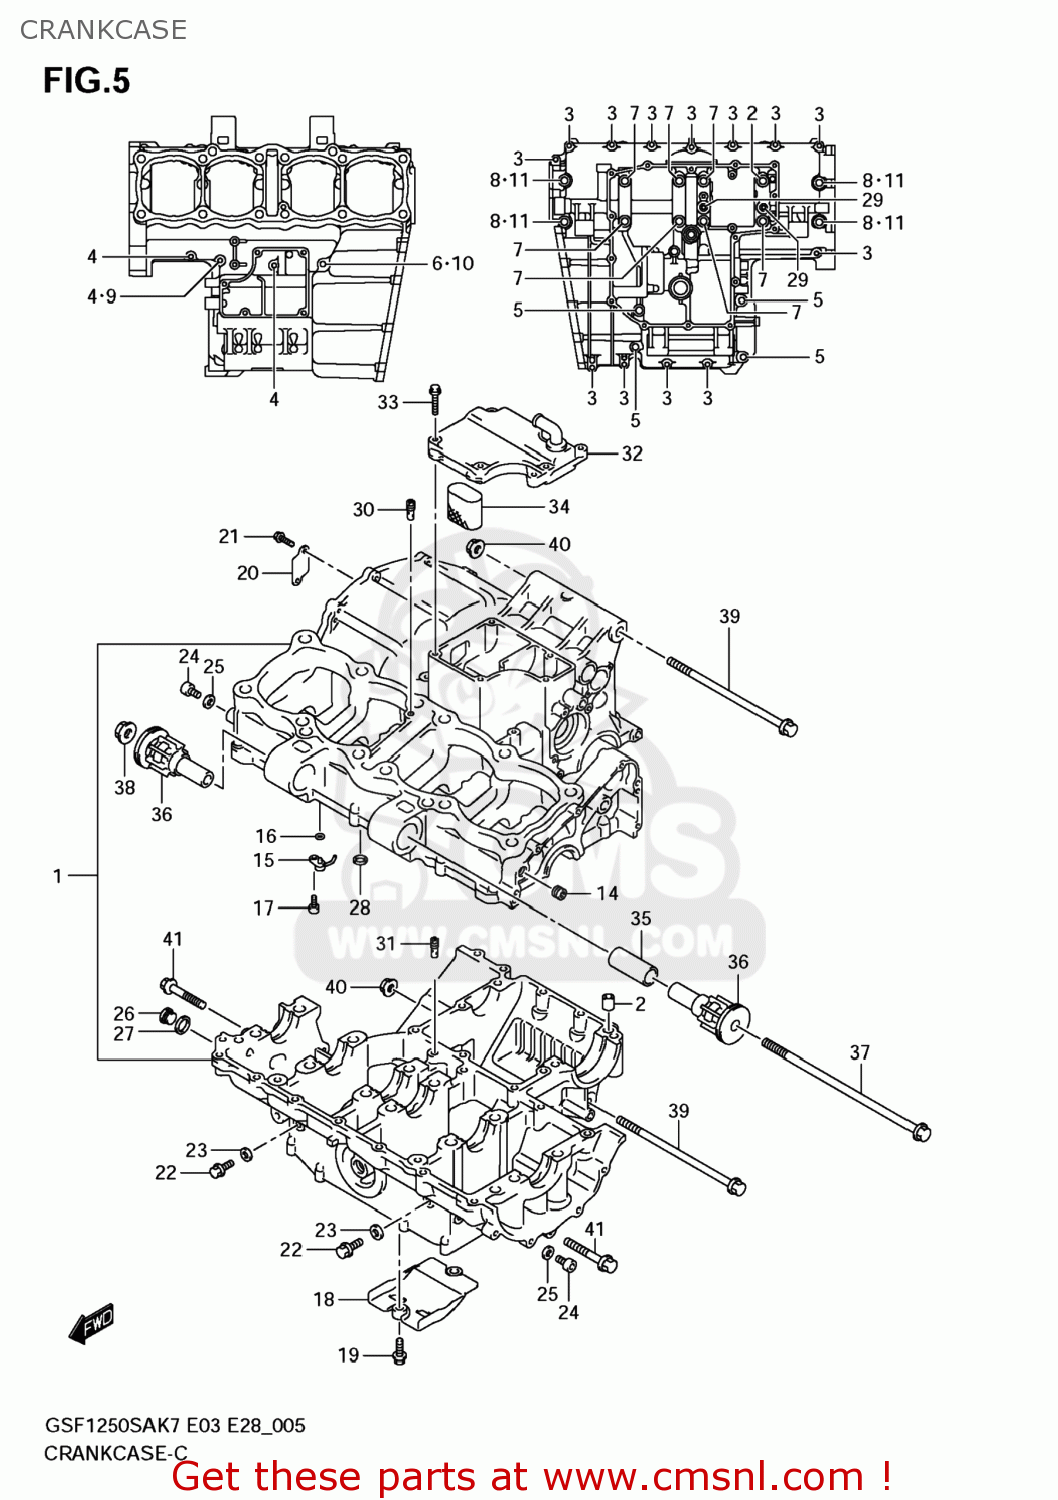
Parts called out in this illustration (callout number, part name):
1	CRANKCASE SET
2	PIN,CRANKCASE
3	BOLT
4	BOLT
5	BOLT
6	BOLT
7	BOLT(9X135)
8	BOLT(9X95)
9	GASKET(5.8X13X1.2) (NAS)
10	GASKET(8.2X14X1) (NAS)
11	GASKET(10.2X20X2).3 (NAS)
12	BEARING,CRANK THRUST(GREEN)
13	BEARING,CRANK THRUST(RED)
14	JET,OIL GALLERY(3.6)
15	JET,PISTON COOLING
16	O RING(D:1.2,ID:4)
17	BOLT(6X12)
18	SEPARATOR,OIL
19	BOLT
20	PLATE,OIL SEPARATOR
21	BOLT
22	BOLT
23	GASKET(6.2X13X1.2) (NAS)
24	BOLT
25	GASKET(8.2X14X1) (NAS)
26	PLUG,16X8
27	GASKET(16X22X2) (NAS)
28	O RING(D:1.9,ID:7.8)
29	O RING(D:1.9,ID:12.6)
30	JET(140)
31	JET,AIR(180)
32	COVER,BREATHER
33	BOLT(6X30)
34	SEPARATOR,OIL BREATHER
35	SPACER,ENG MTG
36	BUSH,ENGINE MOUNTING
37	BOLT 10X215
38	NUT
39	BOLT(12X155)
40	NUT
41	BOLT
